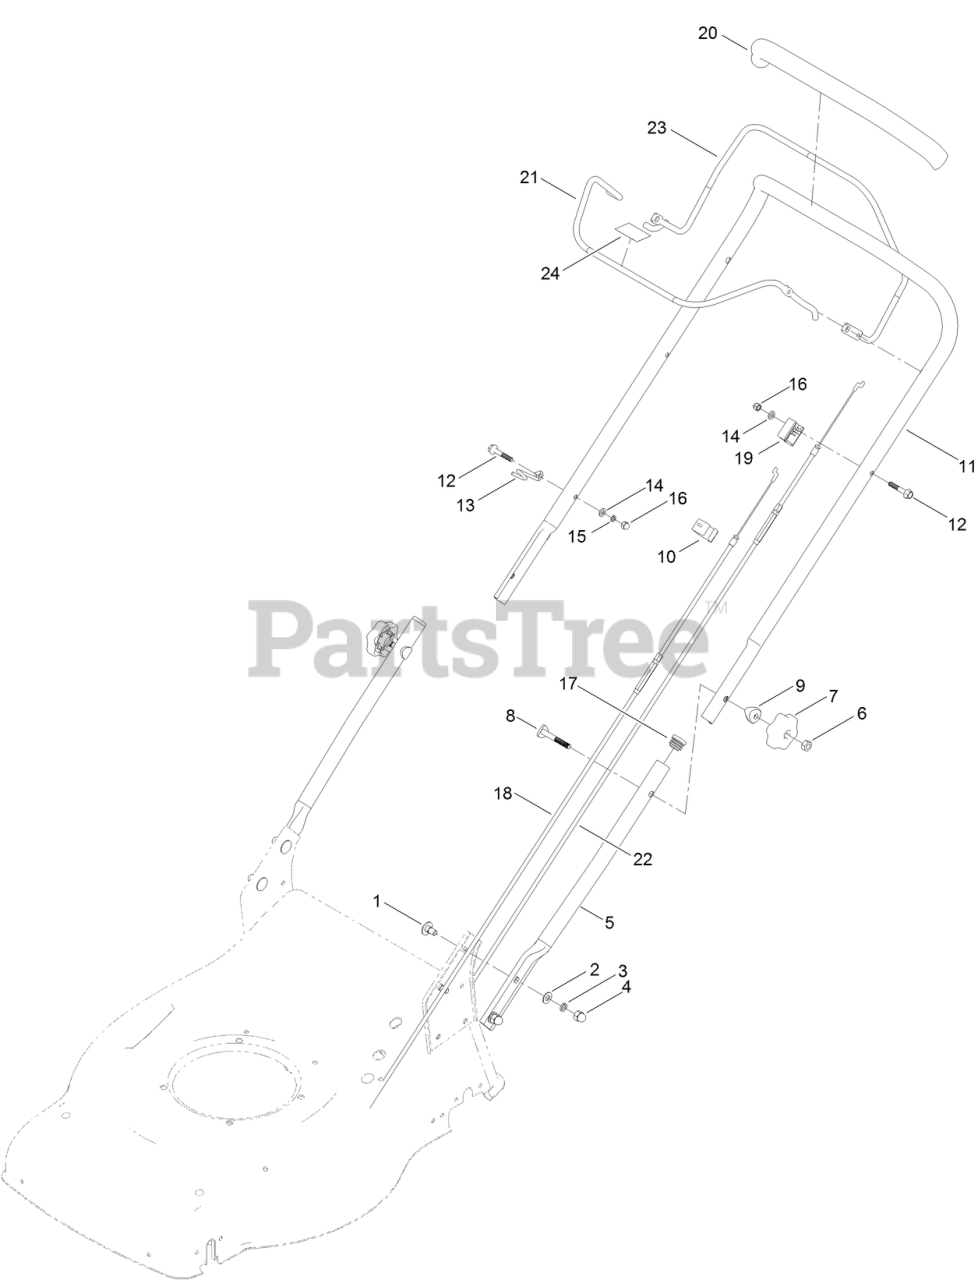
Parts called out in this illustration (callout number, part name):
2	WASHER
3	WASHER-SPRING
4	NUT-LID
5	HANDLEBAR-LOWER
6	NUT-HEX
7	KNOB-ROTARY
8	BOLT-FLAT HEAD
9	WASHER-CURVE
10	CABLE CLAMP
11	HANDLEBAR-UPPER
12	BOLT-HH, FLANGE
13	HOOK-CABLE
14	WASHER-PLAIN
15	WASHER-SPRING
16	NUT-LID
17	PLUG-TUBE
18	CABLE-BRAKE, ENGINE
19	CABLE-BLOCK, FIXED
20	GRIP-HANDLE
21	LEVER-ENGINE
22	CABLE-CLUTCH
23	LEVER-CLUTCH, GEARBOX
24	DECAL-STOP
